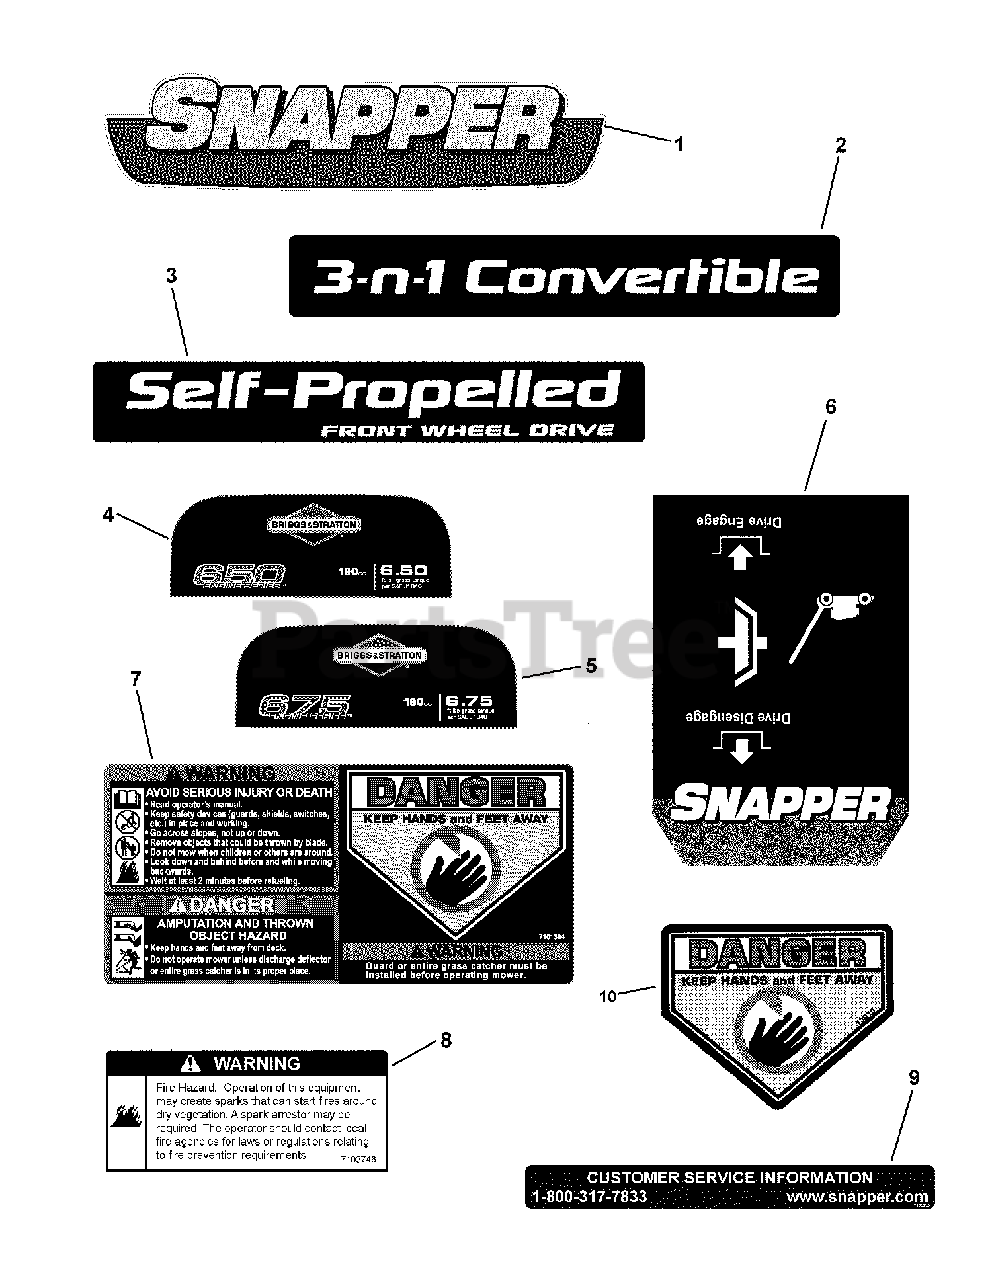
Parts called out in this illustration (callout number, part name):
1	DECAL, Briggs Engine, Snapper
2	DECAL, Front Cover, 22" Snapper, Push
3	DECAL, Front Cover, 22" Snapper, Front Wheel Drive
4	DECAL, Briggs Engine, 650 Series
5	DECAL, Briggs Engine, 675 Series
6	DECAL, Control Head, Single Speed, Snapper
7	DECAL, Warning, Rear Discharge Door
8	DECAL, Spark Arrestor
9	DECAL, Customer Service, MY08, Snapper
10	DECAL, Danger, Cut Finger
